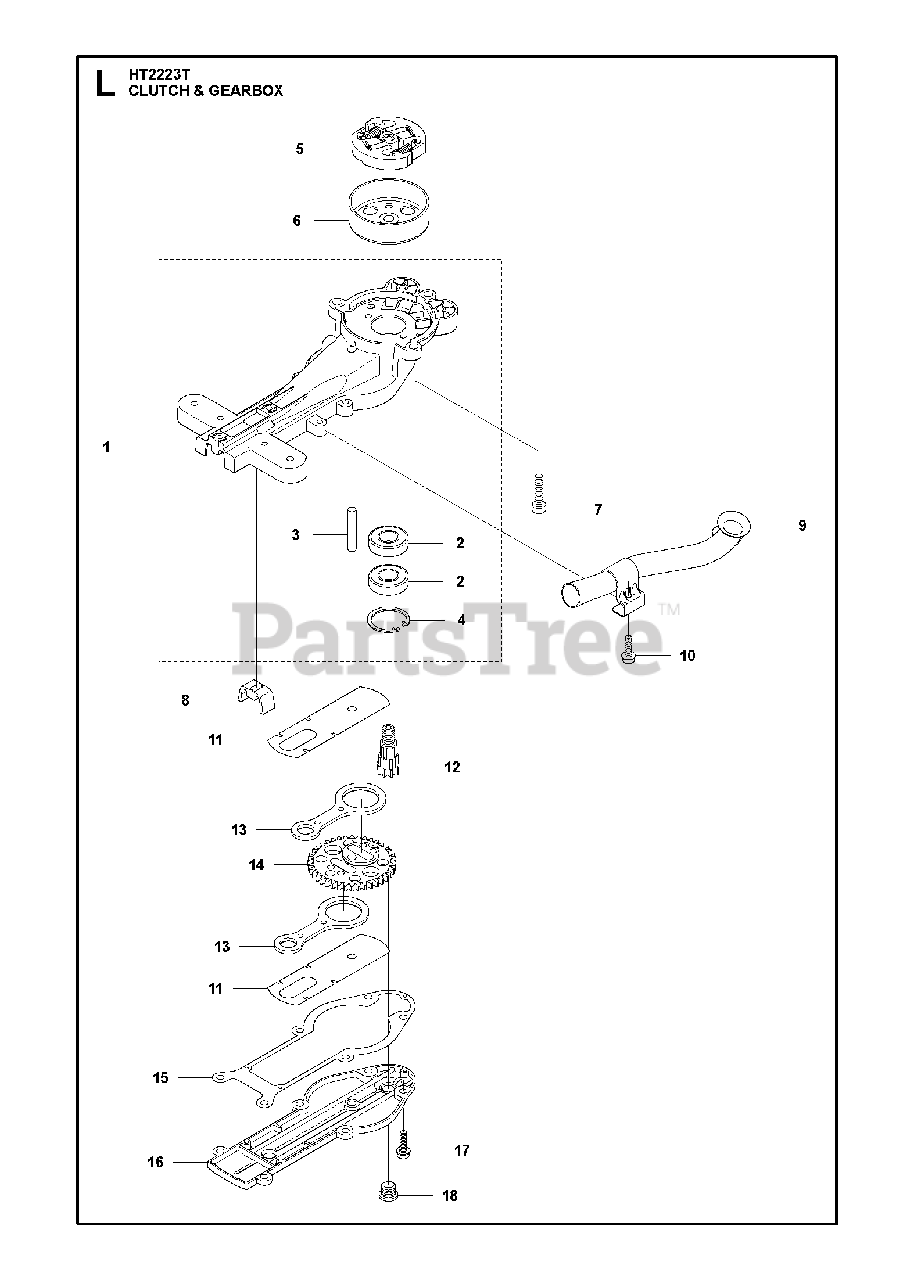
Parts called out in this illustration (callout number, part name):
1	GEAR HOUSING ASSY
2	BALL BEARING
3	PIN
4	CIRCLIP
5	CLUTCH ASSY
6	CLUTCH DRUM ASSY
9	EXHAUST PIPE ASSY.
11	WEAR PLATE
12	GEAR WHEEL SHAFT
13	CONNECTING ROD
14	GEAR WHEEL
